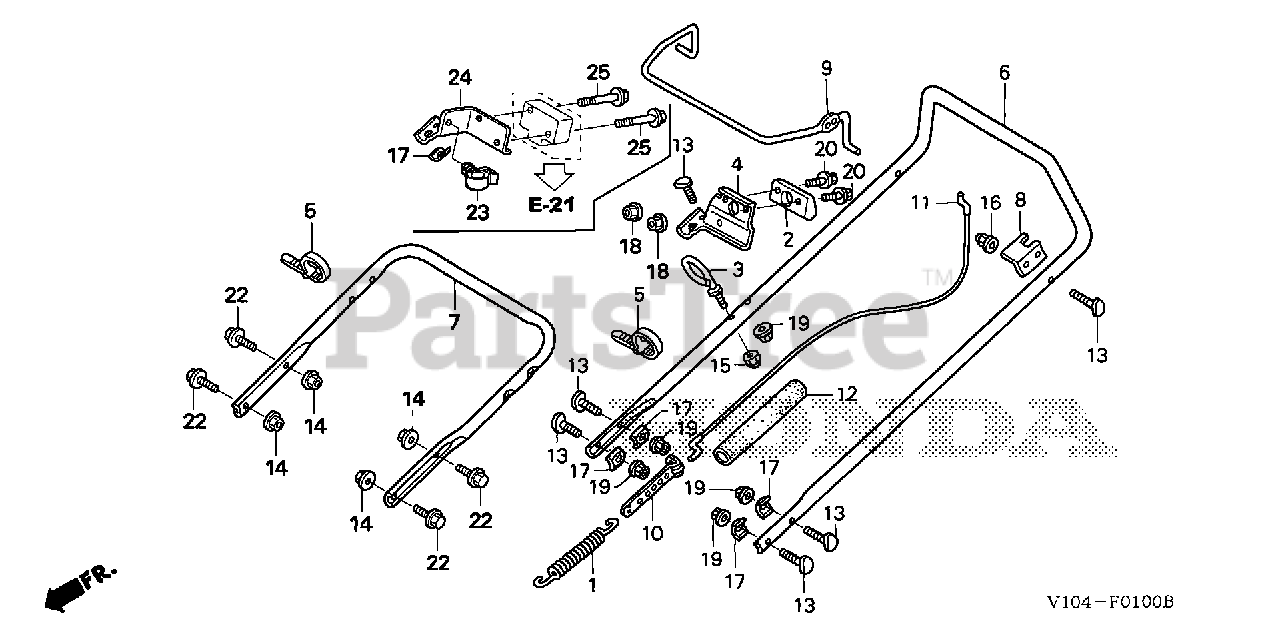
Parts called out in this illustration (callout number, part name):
1	SPRING, BELT TENSIONER
3	GUIDE, ROPE
4	BRACKET, SWITCH BOX
5	TIE, CABLE (157.5MM)
6	PIPE, HANDLE (UPPER)
7	PIPE, HANDLE (LOWER)
8	STOPPER, LEVER
9	LEVER, CLUTCH
10	PLATE, ADJUSTING
11	CABLE, CLUTCH
12	BOOT, CLUTCH CABLE
13	BOLT, HANDLE HOLDER (8X41)
13	BOLT (8X41)
14	NUT, SELF-LOCK (8MM)
15	NUT, NYLON LOCK (6MM)
16	NUT, FLANGE (8MM)
17	WASHER, FRAME JOINT
19	NUT, FLANGE (8MM)
22	BOLT, FLANGE (8X16) Use from Engine SN 1000016.
